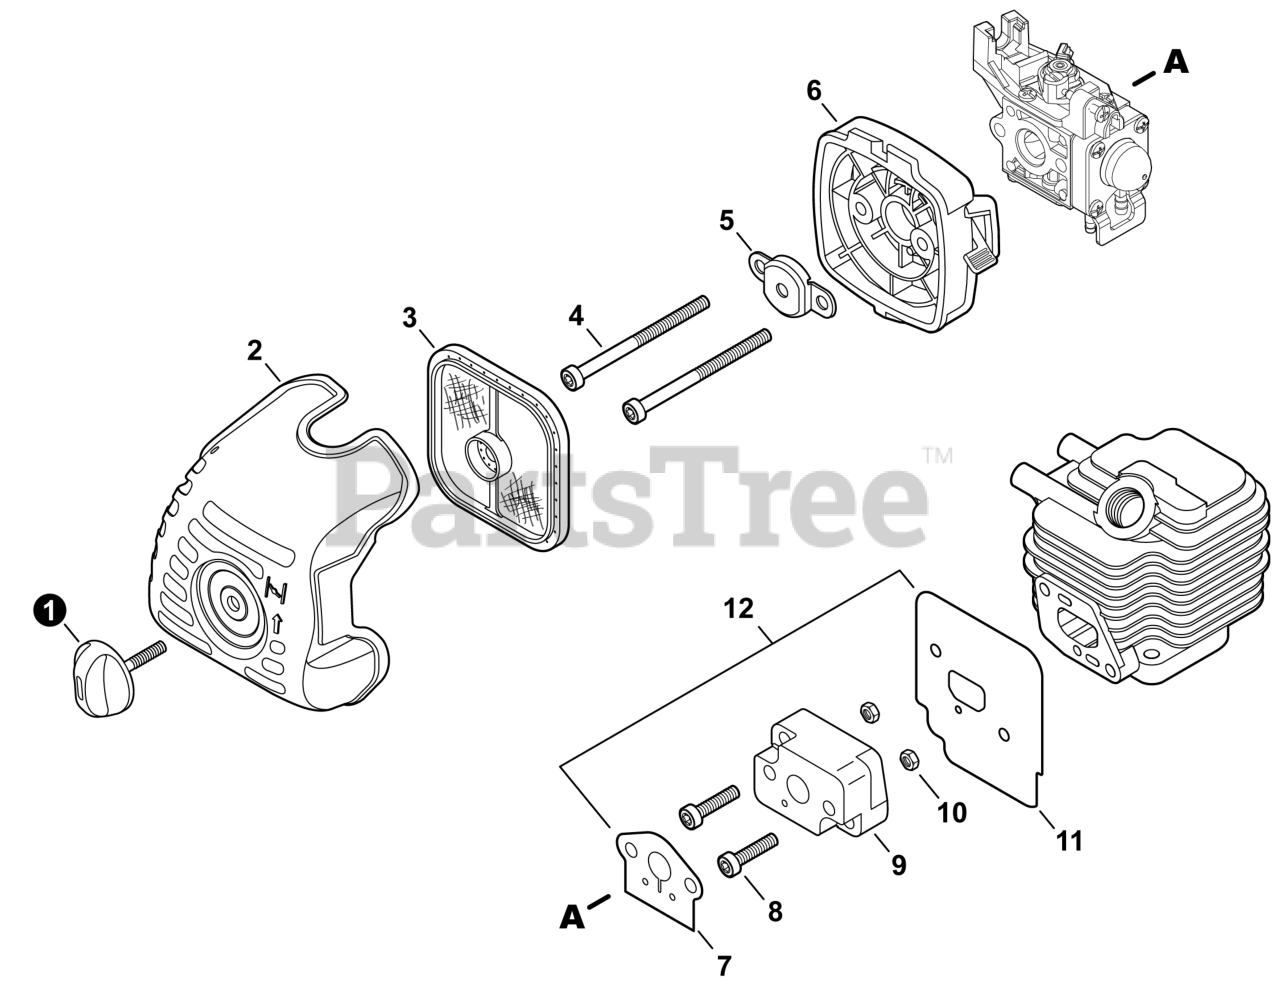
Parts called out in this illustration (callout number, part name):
1	THUMBSCREW
2	COVER, AIR FILTER
3	FILTER, AIR - DOUBLE LAYER
4	BOLT, TORX 5x65
5	PLATE, PREVENT
6	CASE ASSY, AIR FILTER
7	GASKET, INTAKE
8	BOLT, TORX 5x20
9	INSULATOR, INTAKE
11	HEAT SHIELD, INTAKE
12	GASKET KIT: ENGINE, INTAKE, EXHAUST
